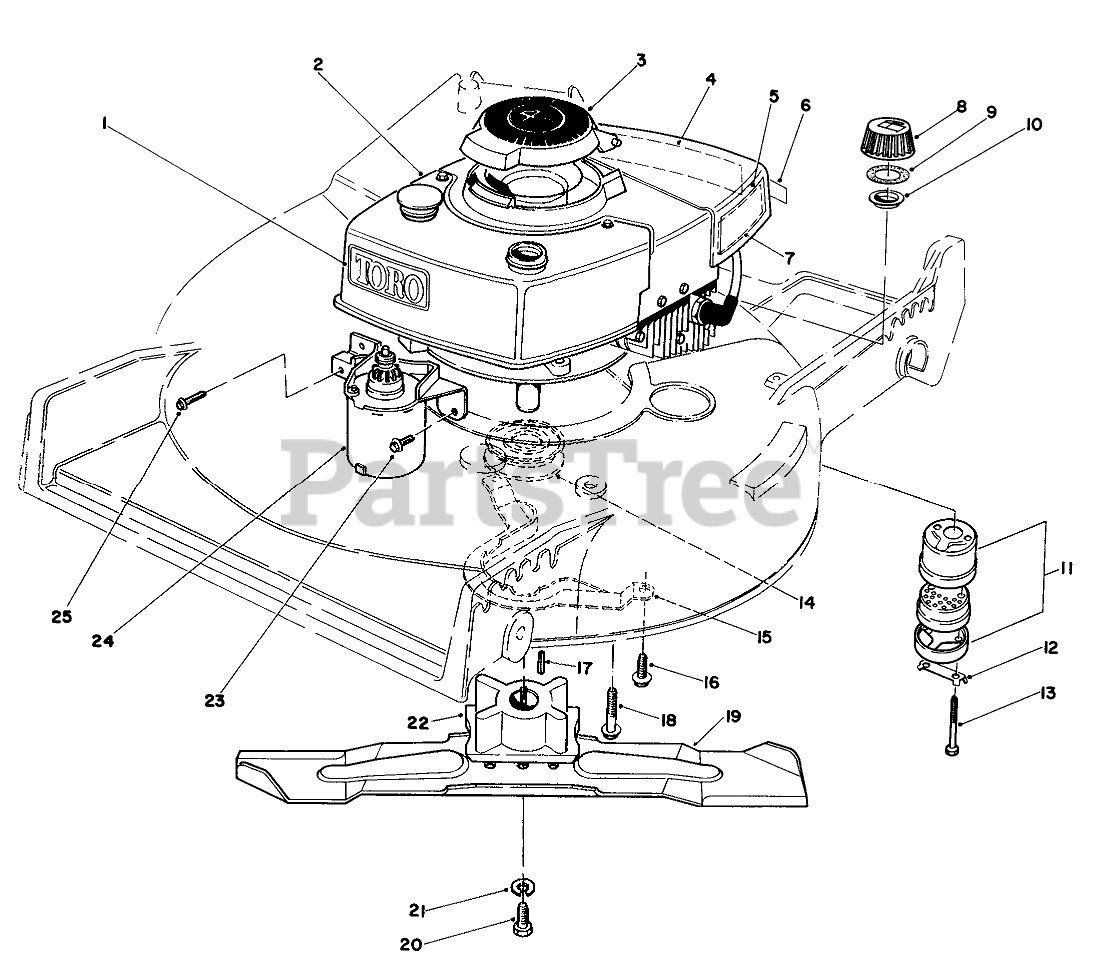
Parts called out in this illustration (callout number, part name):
1	Decal Tow
2	Engine
3	COVER ASM
4	Decal Maintenance
5	Decal-Maintenance
6	Decal-Primer Bulb
7	Decal-Maintenance
8	Gas Cap (Incl. Ref. #9 & 10)
9	GASKET
10	GAS CAP BAFFLE
11	Muffler Assembly (Incl. Ref. #12 & 13)
12	CLIP - LOCKING
13	SCREW-HH
14	Pulley
15	BELT GUIDE
16	Screw
17	KEY-SQUARE
18	3/8-16 X 2 CAPSCREW
19	BLADE-21in
20	SCREW-BLADE
21	WASHER-LOCK
22	BLADE RETAINER(DEEP)
23	SCREW
24	STARTER MOTOR ASM
25	Screw
